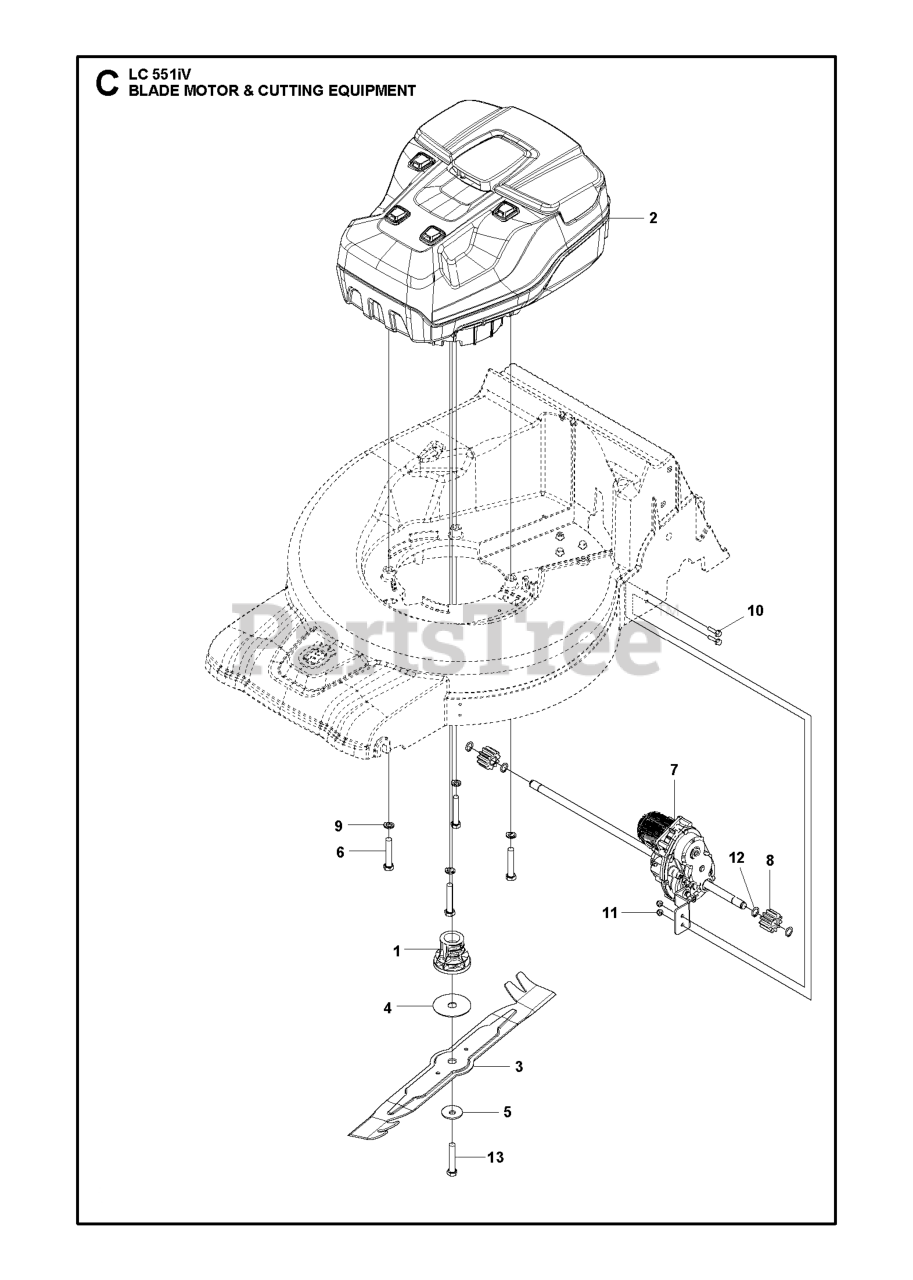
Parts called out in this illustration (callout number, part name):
2	Power Unit
7	Transmissions
9	Spring Washer
10	SCREW M6S 5X20
